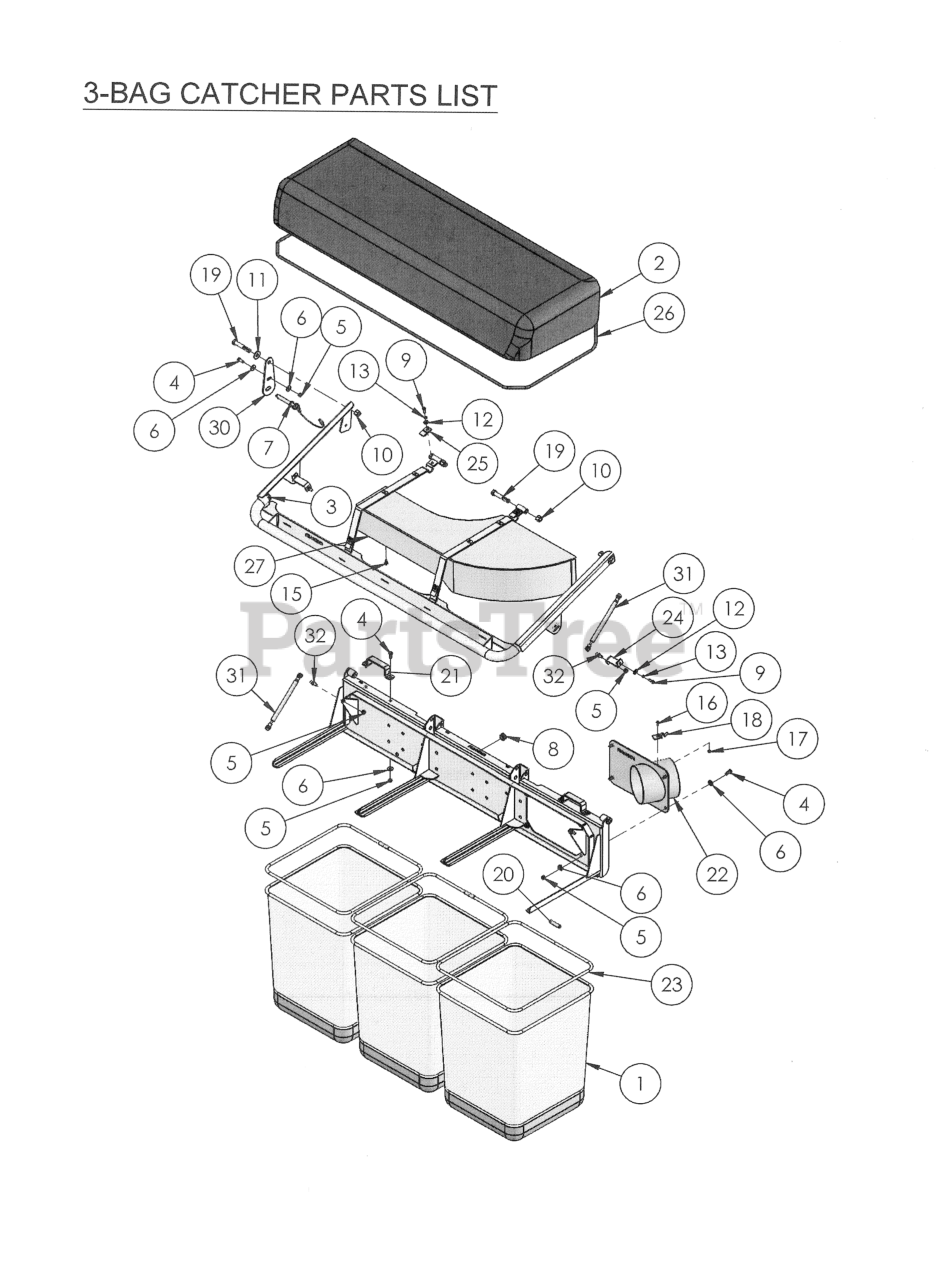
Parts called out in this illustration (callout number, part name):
1	BAG-COMMERCIAL
3	PLUG-1 1/2" TUBE B
4	SCREW 5/16-18 x .75 GR5
5	HEX NUT INS
6	FLAT WASHER 5/16"
7	DETENT PIN 1/2 X 2.5
8	RUBBER BUMPER
9	SCREW 1/4-20X.75 GR5
10	HEX LOCK NUT NYLON
11	FLAT WASHER 1/2"
12	FLAT WASHER 1/4"
13	LOCK WASHER
14	SCREW 1/2-13 x 2.50 GR5
15	BOLT-1/2 X 1/4-20 GR5
16	SCREW #10-24 x .500
18	SPRING CLIP
19	SCREW-HEX 1/2-13 x 3.00
20	CONNECTOR-FRAME PL
23	GRASSBAG FRAME CO
24	BRACKET-GAS CYLINDER MOUNT
25	BRACKET-SINGLE HOL
26	FRAME-AIR DOME 3 B
27	DEFLECTOR-3 BAG
28	SUPPORT-3 BAG MTG
29	SUPPORT-3 BAG CAP
30	ADJUSTMENT LOCK PLATE
31	CYLINDER-GAS
32	BALL JOINT
